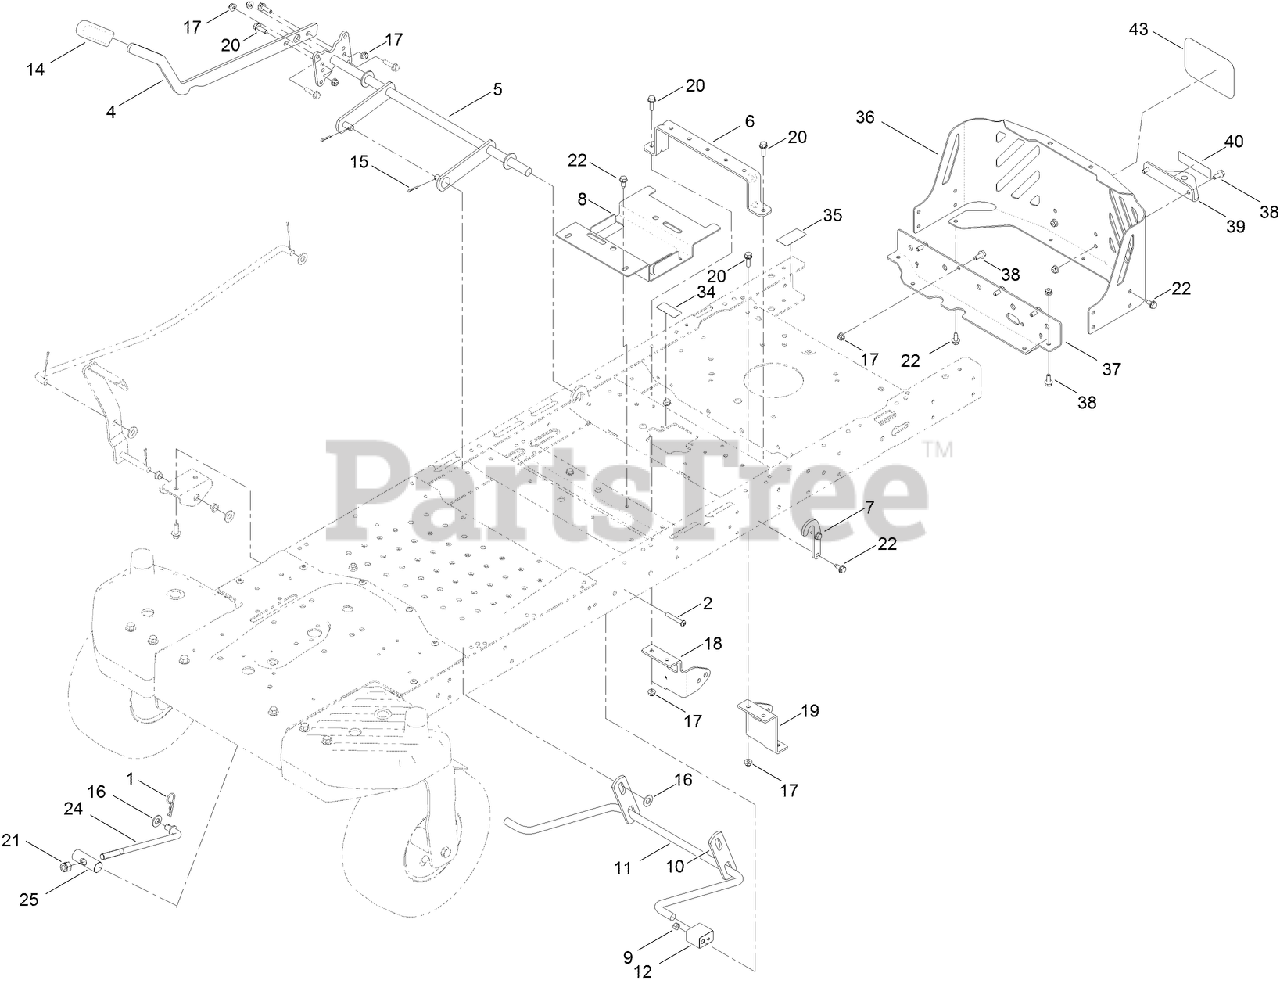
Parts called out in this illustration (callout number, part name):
1	PIN-COTTER
2	SCREW-HSBH
4	LEVER-LIFT
6	BRACE-SEAT, REAR (NARROW)
7	BRACKET-LIFT
8	BRACKET-BATTERY
9	NUT-LOCK, NI
10	LINK-LIFT
11	ARM-LIFT, REAR
12	BLOCK-PIVOT
14	GRIP-LEVER
15	PIN-COTTER
16	WASHER-FLAT
17	NUT-HF, NI
18	MOUNT-HYDRO, FRONT (RH)
19	MOUNT-HYDRO, FRONT (LH)
20	SCREW-HHF
21	NUT-HEX
22	SCREW-HWHTF
24	ROD-MOUNT, DECK
25	PIN-PIVOT
34	DECAL-LOCATION, SERVICE DEALER
35	DECAL-BYPASS
36	GUARD-ENGINE, NARROW
37	CROSSMEMBER-REAR, NARROW
38	SCREW-HHF
39	BRACKET-HITCH
43	DECAL
